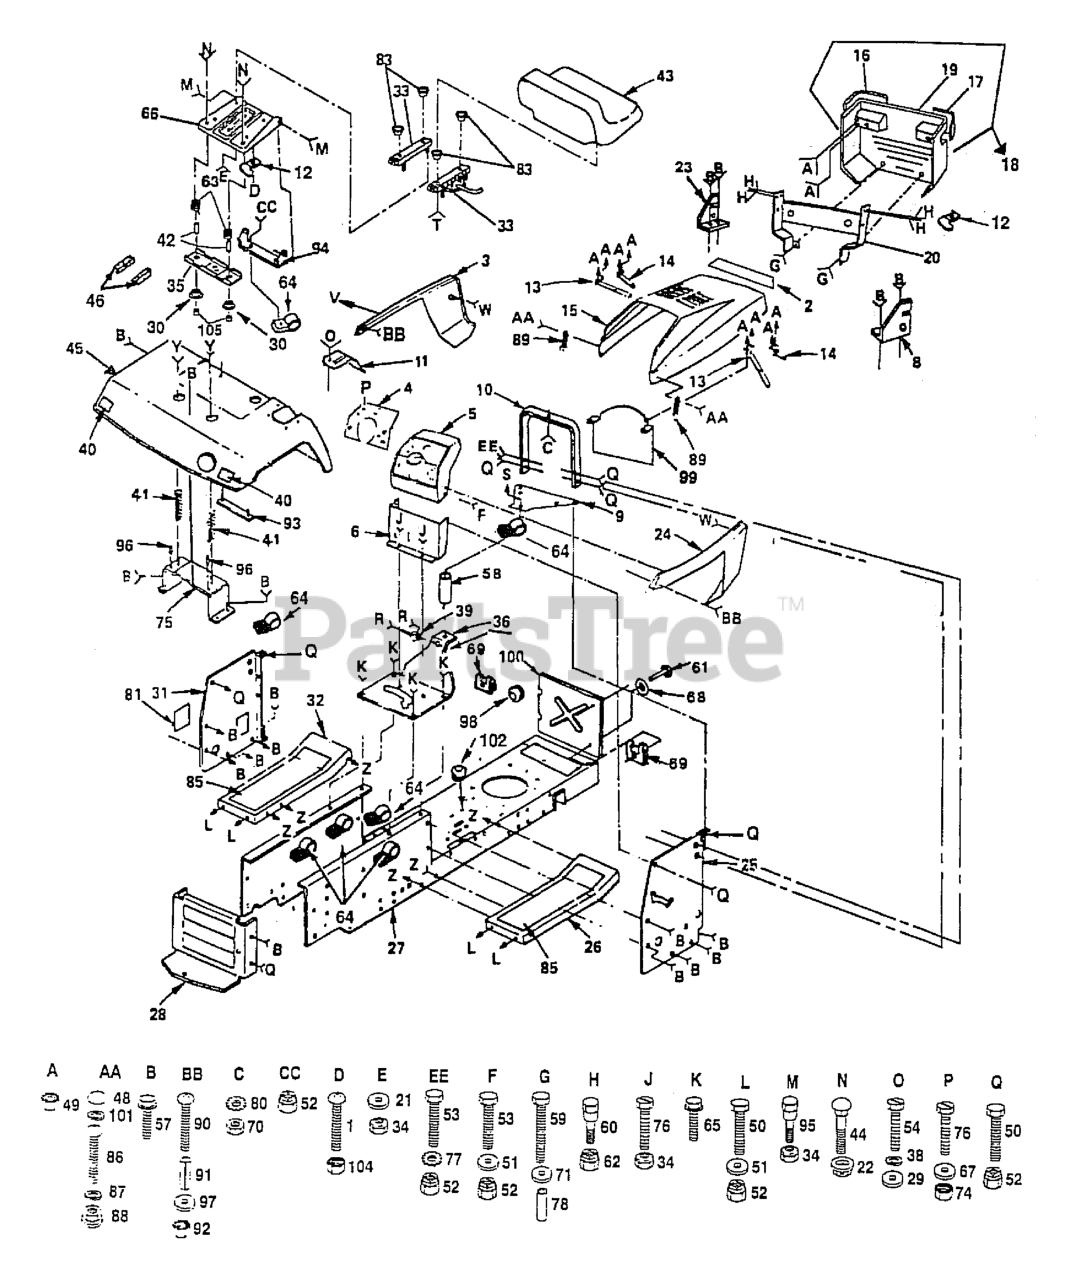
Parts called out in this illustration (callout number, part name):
2	FOAM-STRIP LT
3	PANEL,SIDE LH
4	DASHPLATE
5	DASHBOARD
6	DASH LOWER YT NLA
8	SUPPORT RH YTH
9	PLATE SUPPORT T NLA
10	SUPPORT ASS'Y
11	CONSOLE SHIFTER
13	STRAP ASSY LT
14	STRAP ASSY LT
15	HOOD
16	LENS LH
17	LENS RH
18	GRILL COMPLETE
19	GRILL
20	SUPPORT ASS'Y
22	NUT T
23	SUPPORT LH YTH
24	PANEL,SIDE RH
26	PAD,SPACER
28	DRAW BAR
29	Washer 3/16 x 7/16 x 18 Gauge
31	PANEL DASH LH NLA
32	ROLL PIN NLA
33	SLIDE SET,SEAT
34	LOCKNUT
35	BRKT SWITCH
36	SADDLE
38	WASHER,LOCK
39	BUSHING LT
40	REFLECTOR-TAIL YT
41	SPRING COMPRESSION
42	SPACER, SPLIT
43	SEAT
44	Bolt, Carriage 1/4-20 x 1-1/4
46	STRIP FORM
48	SNAP CAP LT
49	NUT
50	BOLT
51	WASHER
53	BOLT
54	SCREW
57	SCREW
60	BOLT T
61	STUD 1/4 TURN
62	NUT.CROWNLOCK.1/4
63	SPRING COMPRESSED
64	CLIP T
65	SCREW LT
67	WASHER
68	RETAINER LT
69	RECEPTACLE LT
70	NUT
71	WASHER PM
74	NUT
75	BRACKET-FENDER YT
76	Screw, Mach 5/16-18 x 3/4
77	LOCKWASHER
80	Washer, Lock 1/4 Int./External
81	COVER ACCESS
85	PAD FOOTREST T
86	SCREW
88	WELDNUT
89	LATCH.HOOD.
90	RP SCREW
92	NUT **
93	STRAP-FENDER YT
94	BRKT,SEAT PIVOT
95	BOLT, SHOULDER LT
96	NUT-PUSH YT
98	SNAP BUSHING T
99	BAFFLE,REAR UPPER
100	SHIELD HEAT HYT
102	SNAP BUSHING T
104	Nut, Keps #10-32 UNC
105	CAP SPRING
